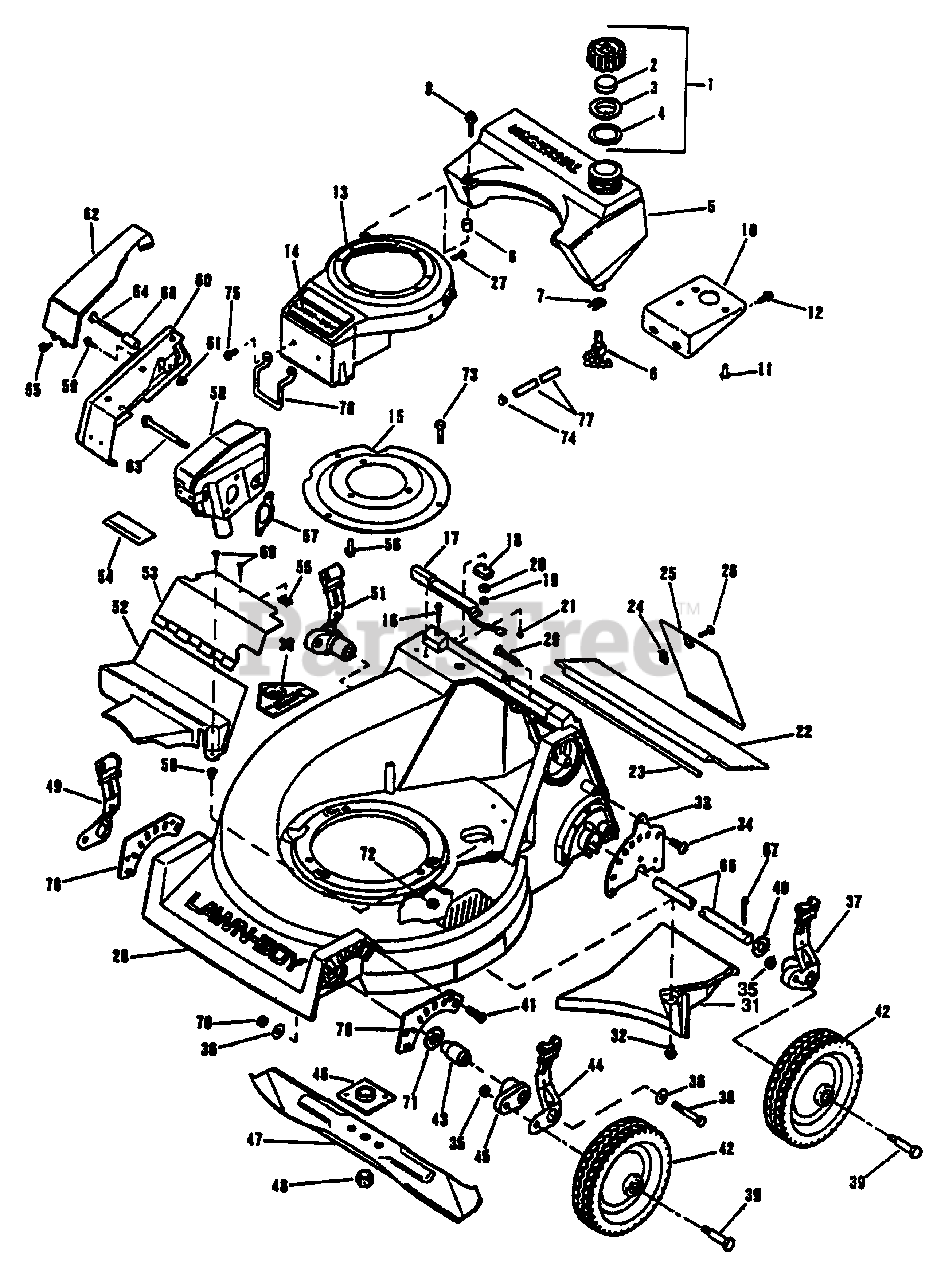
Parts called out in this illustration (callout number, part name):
1	Fuel Cap Assy (Inc. 2-4)
2	Baffle
3	Baffle-Cover
4	Gasket
5	Fuel Tank
6	Valve & Screen
7	Clamp
8	Spacer
9	Screw-Fuel Tank to Shroud
10	Fuel Tank Mounting Bracket
11	Screw-Fuel Tank to Bracket
12	Screw-Tank Bracket to Block
13	Shroud & Applique Assy (Inc. 14)
14	Applique
15	Engine Mounting Plate
16	Screw-Magnet to Housing
17	Bag Interlock Switch
18	Magnet
19	Nut-Magnet to Housing
20	Lockwasher-Magnet to Housing
21	Screw-Interlock Switch to Housing
22	Trailing Shield
23	Trailing Shield Pivot Rod
24	Speed Nut
25	Access Door
26	Screw-Access Door to Housing
27	Screw-Shroud to Engine
28	Housing Assy (Inc. 29-32)
29	Handle Mounting bolt
30	Decal-Blade Contact Warning
31	Baffle-Chute Floor
32	Screw-Baffle to Housing
33	Height Adjust Plate
34	Screw-Plate to Housing
35	Nut-Front Wheel Bolt
36	Washer-Front Height Adjust Arm
37	Rear Height Adjust Arm-LH.
38	Screw-Front Height Adjust Arm
39	Shoulder Bolt-Wheel
40	Washer
41	Flat Head Screw
42	Wheel & Tire Assembly
43	Front Height Adjust Bushing
44	Knob & Spring Assy-Front L.H.
45	Front Height Adjust Arm
46	Collar & Plate
47	21" Blade
48	Nut-Blade
49	Knob & Spring Assy-Front R.H.
50	Grommet
51	Rear Height Adjust Arm-R.H.
52	Lower Drive Cover
53	Upper Drive Cvr w/Decal (Inc. 54)
54	Decal-Warning
55	Speednut
56	Screw-Mounting Plate to Engine
57	Exhaust Gasket
58	Muffler
59	Screw-Muffler Guard
60	Muffler Guard Assy (Inc. 61-62)
61	Pushnut
62	Muffler Cover
63	Screw-Muffler
64	Screw-Muffler Guard
65	Screw-Muffler Guard
66	Height Adjust Pivot Rod
67	Cotter Pin
68	Spacer-Muffler Guard
69	Screw-Drive Cover to Housing
70	Nut
71	Flat Washer
72	Locknut-Mting Plate to Housing
73	Screw-Mtg Plate to Housing
74	Clamp-Fuel Line to Carburetor
75	Hex Flange Head Screw
76	Spark Plug Guard
77	Fuel Line
78	Front Height Adjust Plate-R.H.
79	Front Height Adjust Plate-L.H.
